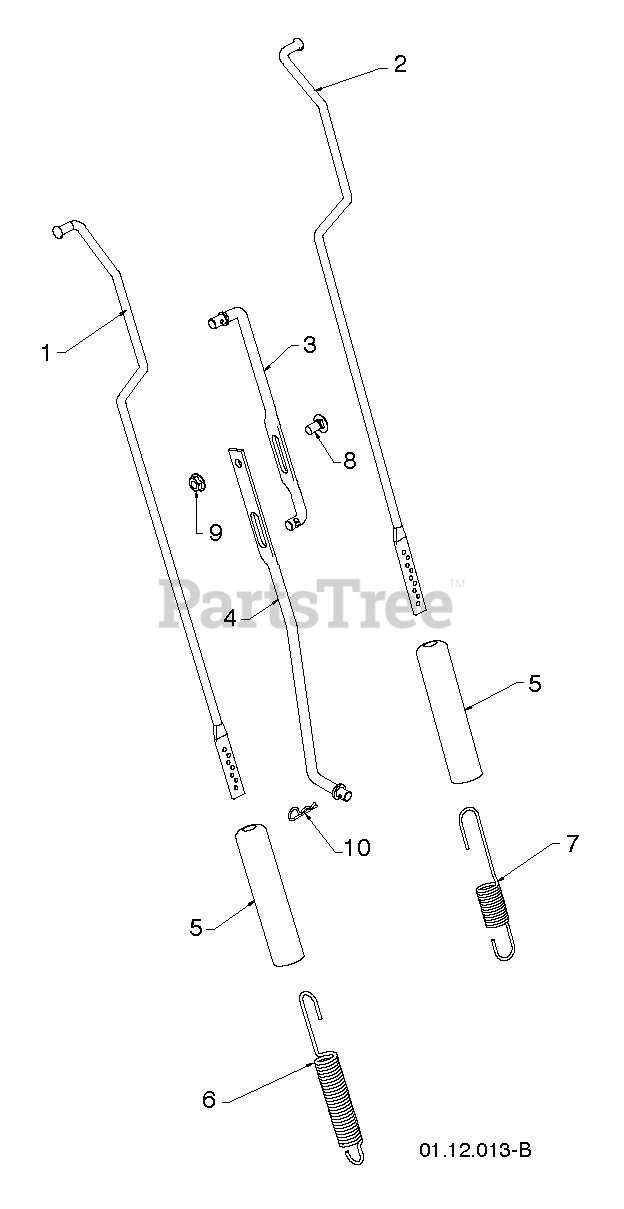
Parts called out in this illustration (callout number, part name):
1	ROD.IMPELLER
2	ROD.TRACTION
3	ROD, UPPER SPEED CONTROL
4	ROD, LOWER SPEED CONTROL
5	SLEEVE, SPRING
6	SPRING.CONTROL.ROD.SNOW
7	SPRING.TRACTION.ROD.SNOW
8	BOLT
9	NUT.FLANGE.5/16
10	SPRING RETAINER
